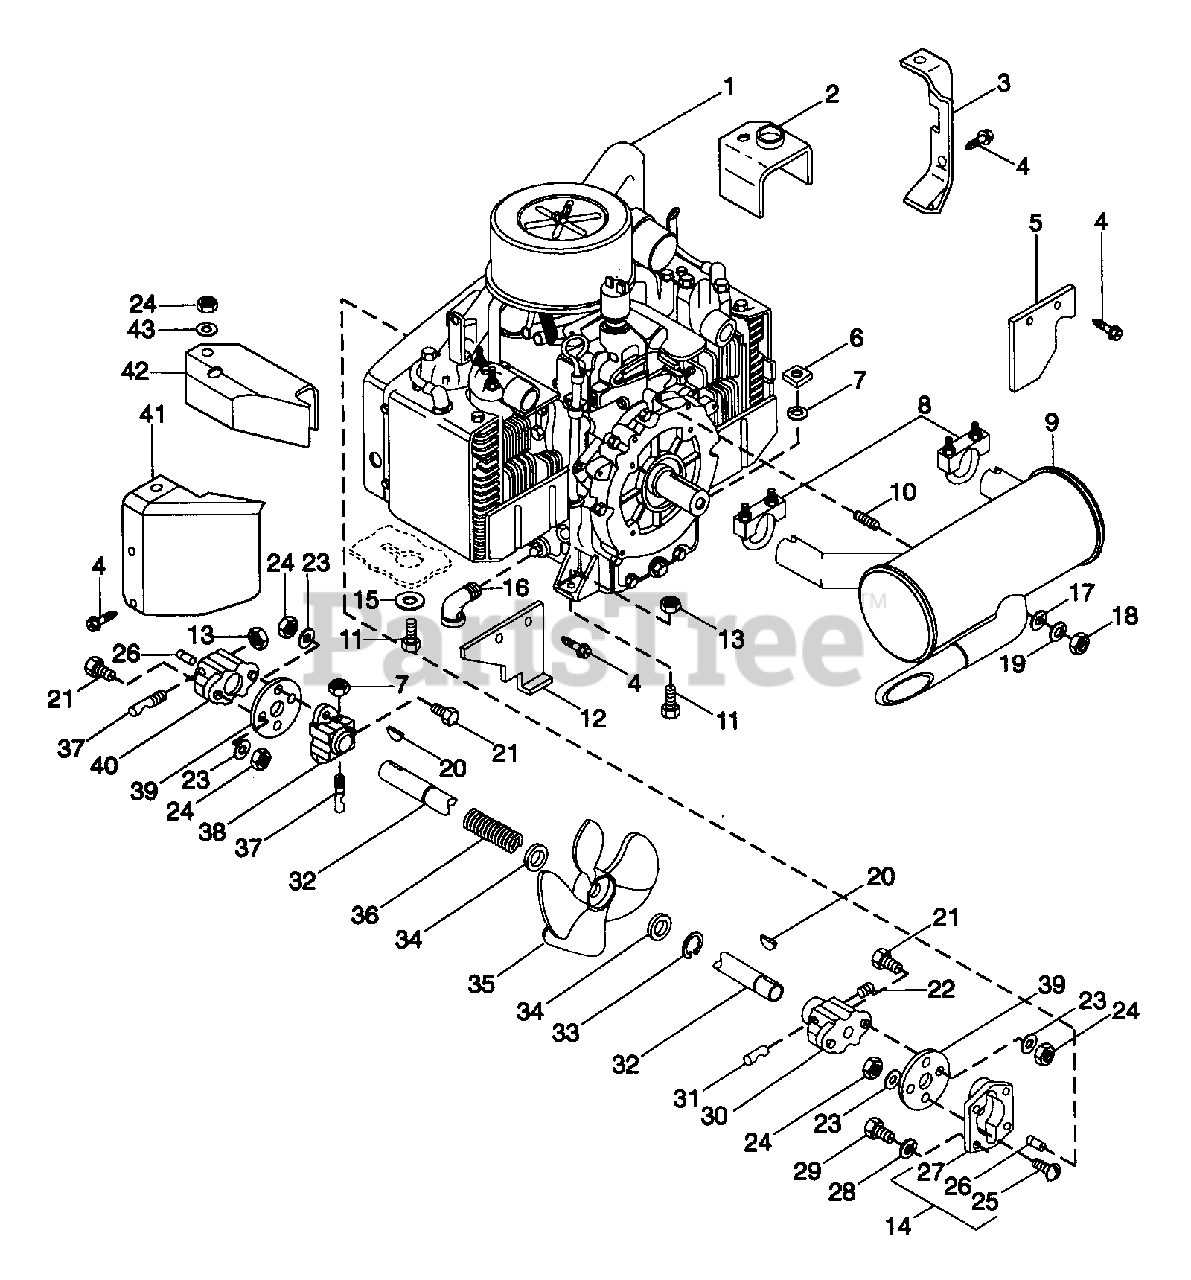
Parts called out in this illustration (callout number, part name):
1	KOHLER M18S #24513
1	KOHLER M20S #49533
2	LEFT EXHAUST SHIELD
3	LH CYLINDER BAFFLE
4	SCR-TAP 12-14X.62 HWH PL B
5	L.H. BAFFLE
6	NUT-SPECIAL-HDND .38-16 GR5 PL
7	WSHR-LK .375X.115 HVY PL
8	EXHAUST CLAMP - 1 1/2
9	MUFFLER-TWIN EXHAUST
10	ENGINE STUD
11	BLT-HEX .38-16X1.25 PL GR5
12	R.H. BAFFLE
13	NUT-LK TOP .375-16 GR C YWZC
14	ENGINE COUPLING ASSEMBLY - TWI
15	WSHR-FL-STL .38X.875X.083 PL
16	STREET ELBOW
17	WSHR-FL-STL .250X.562X.049 PL
18	WSHR-LK .250X.077 HVY PL
19	NUT-HEX .250-20 PL
20	KEY-WDRF .188X.75X.313 SAE 9
21	BLT-HEX .31-18X.88 PL GR2
22	SCR-SET .38-16X.50 SKHCUP OH
23	WSHR-FL-STL.344X.688X.065PL
24	NUT-LK .312-18 GR A PL
25	BLT-SERRDHD SL .31-18X.87 PL
26	PIN-GRV .313X.75 TP D
27	DRIVE HUB - FLYWHEEL TWIN
28	WSHR-LK .375X.094 MED PL
29	@BLT-HEX .38-16X.88 PL GR2
30	DRIVE HUB- TWIN SHAFT
31	LOCK STUD
32	DRIVE SHAFT
33	RG-RTNG-EXT .750X.042
34	WSHR-HDND-THRST .758X1.23X.031
36	SG-COMP .120X.75X2.50 WLD48
37	LOCK STUD
38	DRIVE HUB
39	SPACER COUPLING
40	DRIVE HUB - HYDRO
41	R H CYLINDER BAFFLE
42	RIGHT EXHAUST SHIELD
43	WSHR-FL-STL .323X.625X.062 PL
